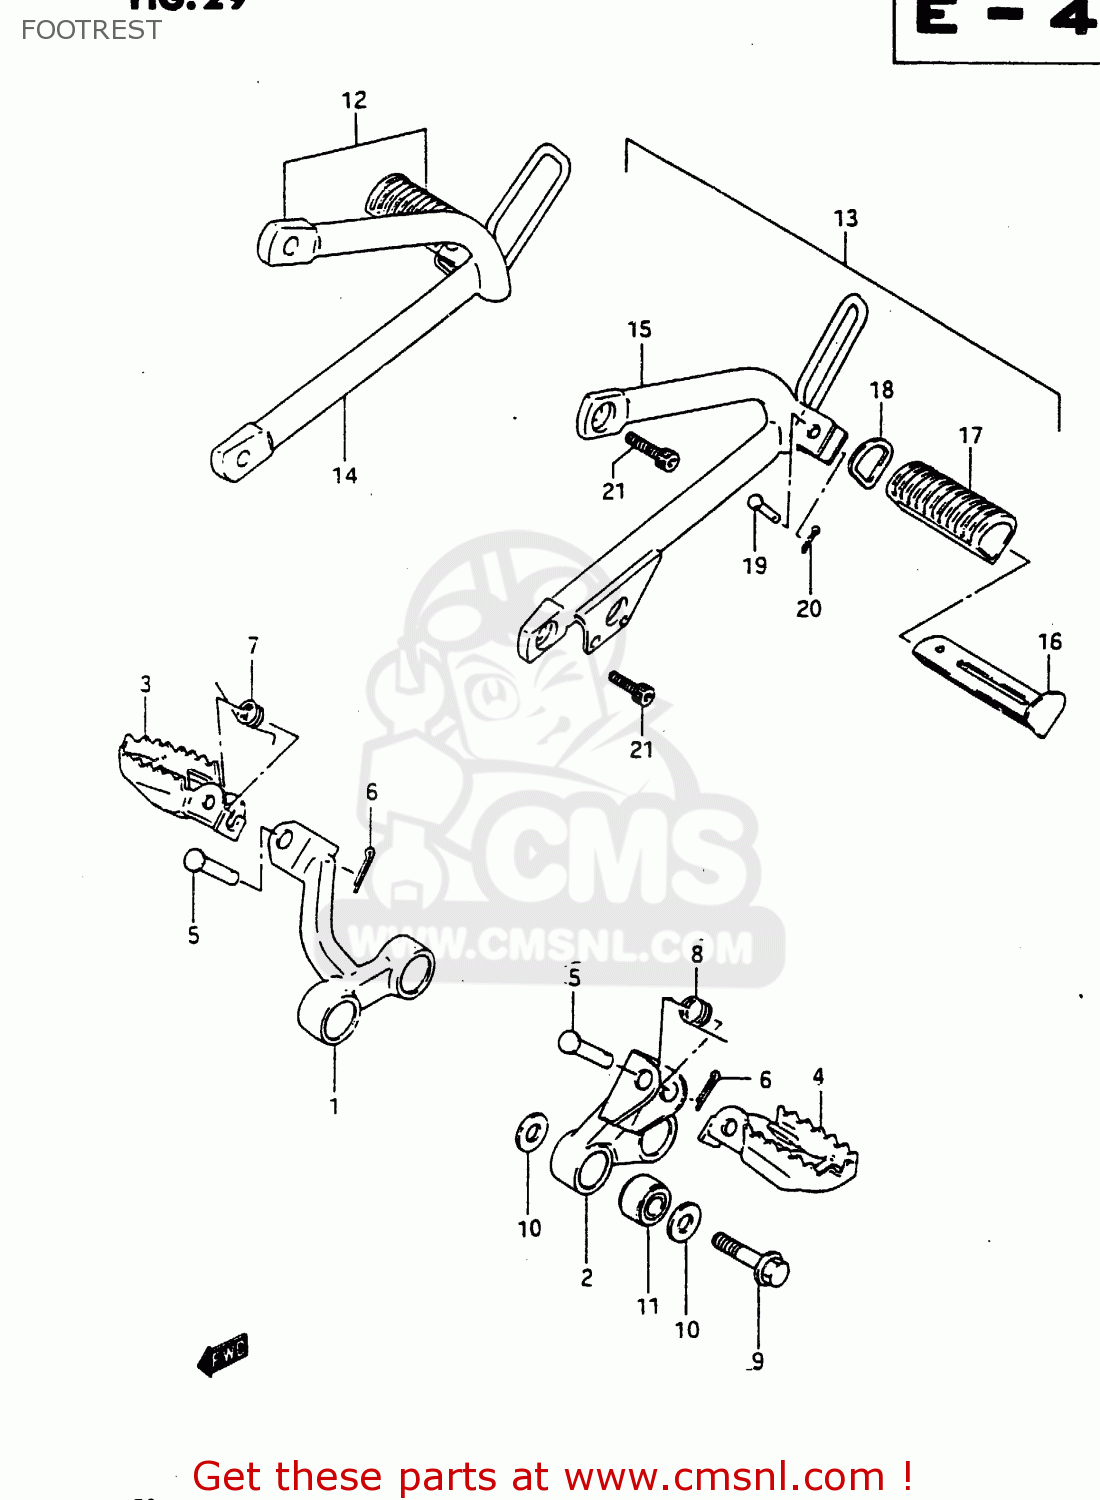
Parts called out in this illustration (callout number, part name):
1	BAR, FOOTREST RH (BLUE)
2	BAR, FOOTREST LH (BLUE)
3	FOOTREST, FRONT RH (BLUE)
4	FOOTREST, FRONT LH (BLUE)
5	PIN
6	PIN 20X20
7	SPRING
8	SPRING
9	BOLT(10X50)
10	WASHER
11	BUSH(10.2X25X19)
12	FOOTREST, PILLION RH (BLUE)
13	FOOTREST, PILLION LH (BLUE)
14	HOLDER, RH (BLUE)
15	HOLDER, LH (BLUE)
16	BAR COMP,PILLION FOOTREST
17	RUBBER,PILLION FOOTREST
18	WASHER,PILLION FOOTREST
19	PIN
20	PIN
21	BOLT
